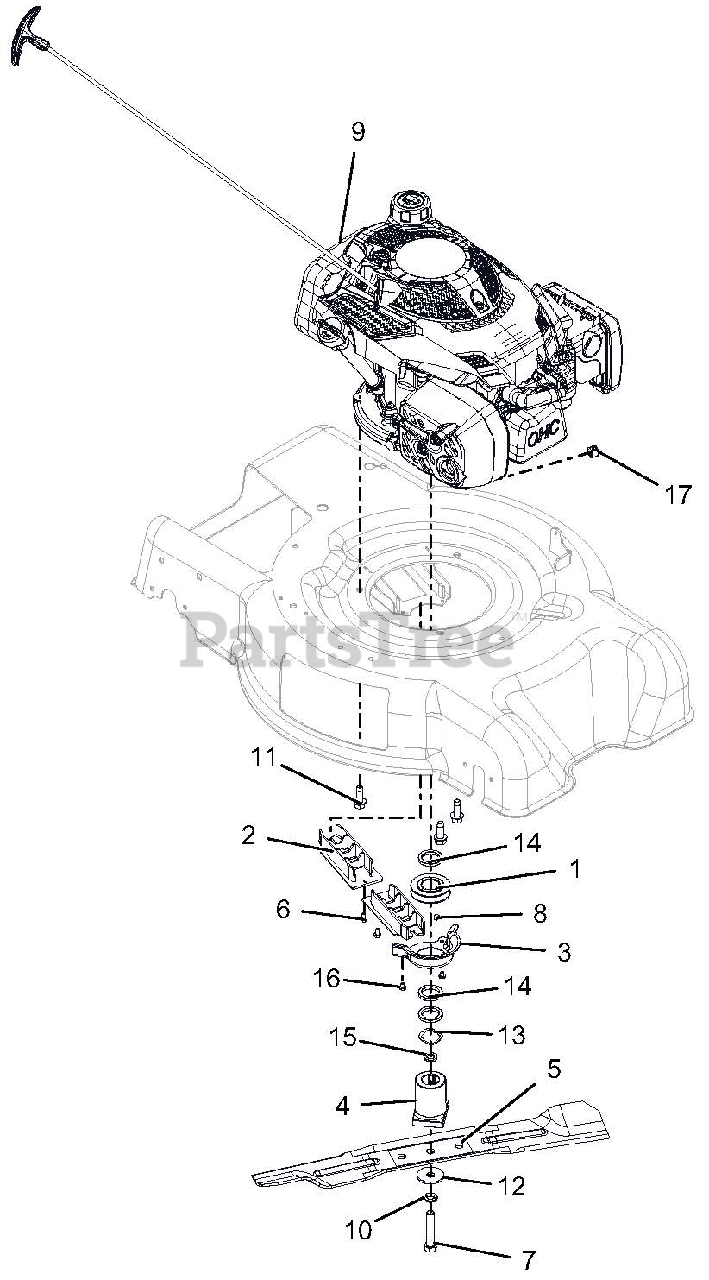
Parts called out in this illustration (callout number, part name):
1	PULLEY,MACHINED POWDER METAL
2	GUIDE, BELT INNER
3	GUIDE, BELT CRANK
4	ADAPTER, BLADE
5	BLADE, MOWER 21" HIGH LIFT
6	SCR-TAP 10-24X.375 PRE-COAT 80
7	@BLT-HEX .4375-20X2.25 GR8 YWZ
8	KEY-SQ .188X.188X.250
9	ENGINE, SUBARU 175CC VERT
10	@WSHR-LK .44X.109 REG YWZC
11	@SCR-TAP .38-16X1.00 HWH TR YZ
12	WSHR-FL-STL .4375X1.50X.125 YZ
13	WASHER - WAVE 1.09X1.37X.016
14	SPCR, 1.00 X 1.375 X .179
15	WSHR-FL-STL .459X.750X.105 YZC
16	SCR-TAP 10-24X.25 CRSLPH TR YZ
17	PLUG, DOME-BLACK, .625 DIA
